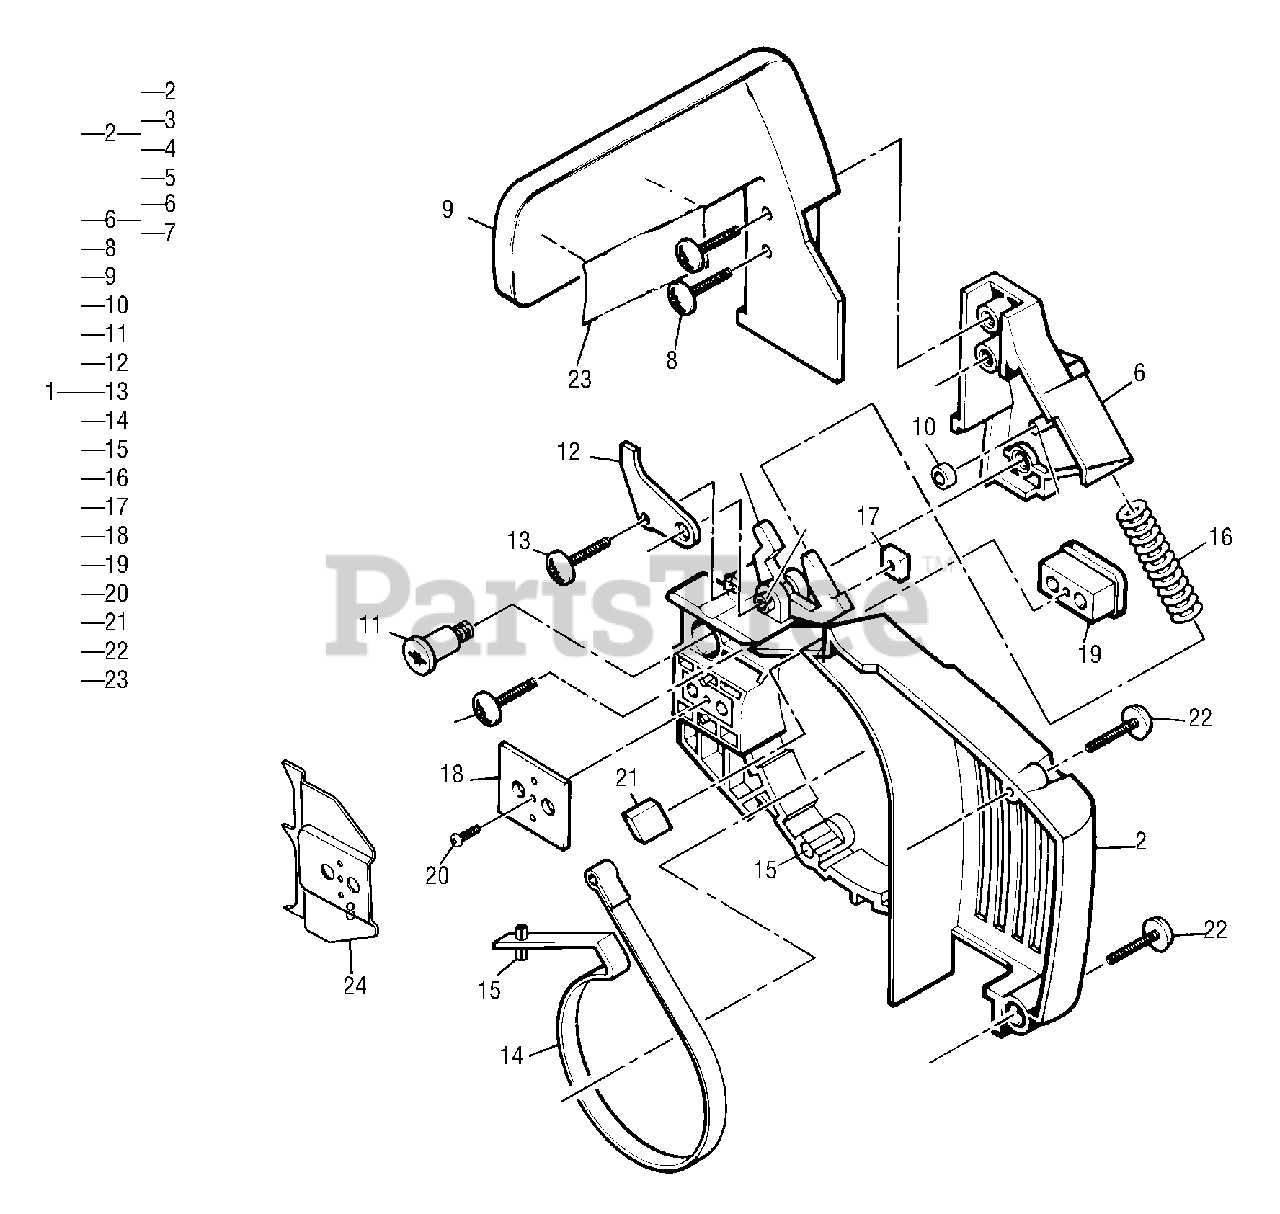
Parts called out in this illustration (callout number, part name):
1	Brake Kit Asy, Yellow
2	Housing Kit Asy, Yellow
3	Latch, Chain Brake
4	Dowel, Spring
5	Pin, Dowel
6	Lever, Actuating
7	Pin, Dowel
8	Screw, 10-24 x .62 Tr Hd Torx
9	Guard, Hand
10	Roller
11	Screw, Shoulder
12	Stop, Brake
13	Screw, 8-16 x .75 Tr Hd Plastite
14	Band, Brake
16	Spring, Compression
17	Nut, Square 10-24
19	Spacer, Bar Pad
20	Screw, 4-40 x 5/16 Taptite
21	Seal, Foam
22	Screw, 8-16 x 1.0 Tr Hd Plastite
23	Label, Safety
24	Spike, Bucking
